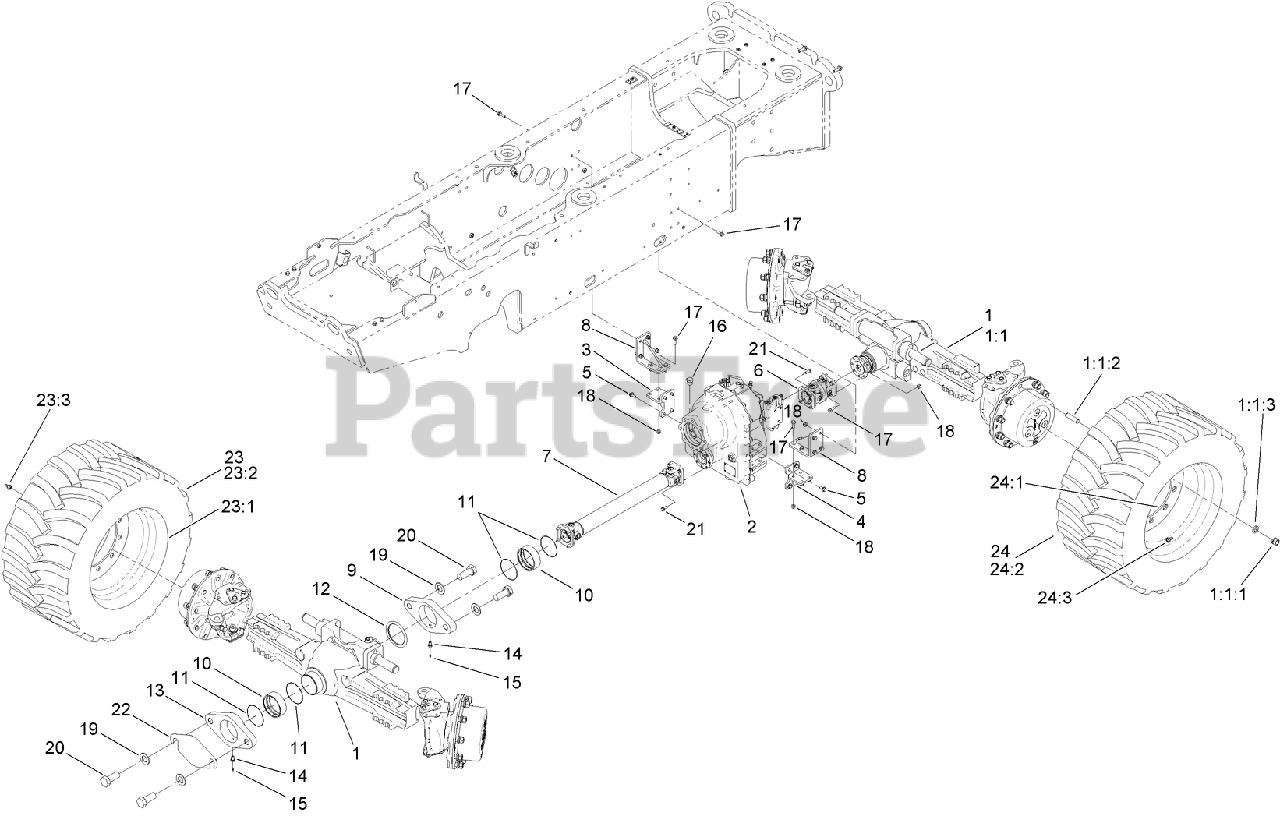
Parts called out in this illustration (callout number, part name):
1	AXLE ASM
1:1	Axle
1:1:1	NUT-LUG
1:1:2	STUD-WHEEL
1:1:3	WASHER-LOCK
2	TRANSMISSION-2 SPEED, POWERSHIFT
3	MOUNT-TRANSMISSION, RH
4	MOUNT-TRANSMISSION, LH
5	SCREW-HHF
6	CONSTANT VELOCITY JOINT ASM
7	FRONT AXLE DRIVE SHAFT ASM
8	MOUNT-TRANSMISSION
9	HOUSING-MOUNT, TRUNION
10	BUSHING-PIVOT
12	WASHER-THRUST
13	HOUSING-MOUNT, TRUNION
14	ADAPTER-LOCATING
15	FITTING-GREASE
16	PLUG-HYD
17	SCREW-HHF
18	NUT-LOCK, NI
21	SCREW-HHF
22	SHIM-MOUNT, AXLE
23	RH TIRE ASM
23:2	TIRE-TRENCHER
23:3	STEM-VALVE
24	LH TIRE ASM
24:2	TIRE-TRENCHER
24:3	STEM-VALVE
